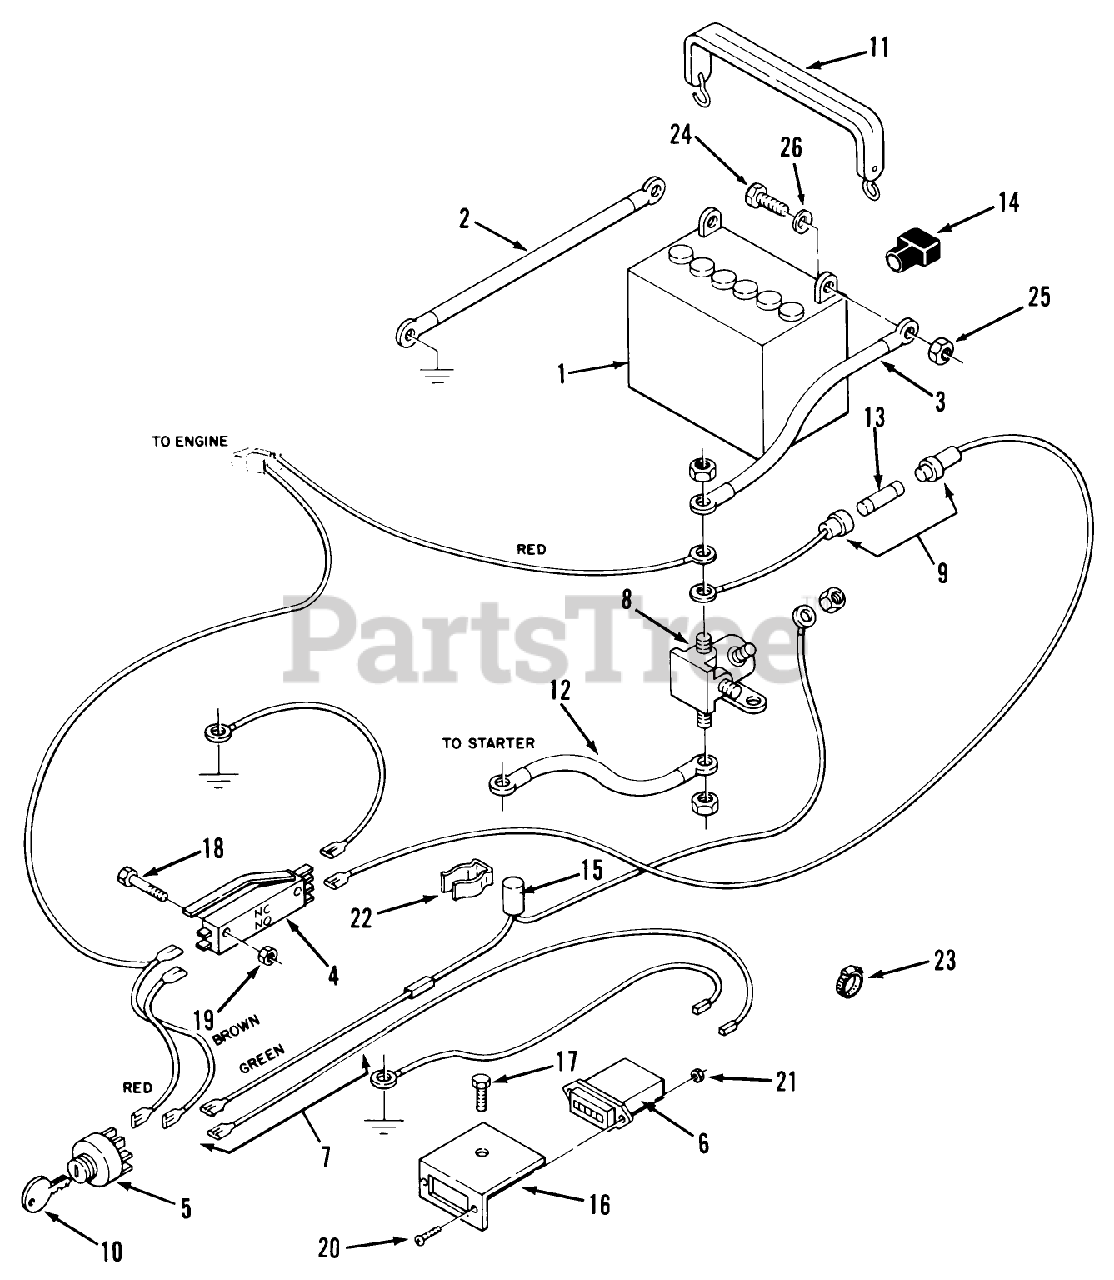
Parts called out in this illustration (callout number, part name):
4	SAFETY SWITCH
5	SWITCH ASSY
8	SOLENOID
11	DISC-OBTAIN LOCALLY
